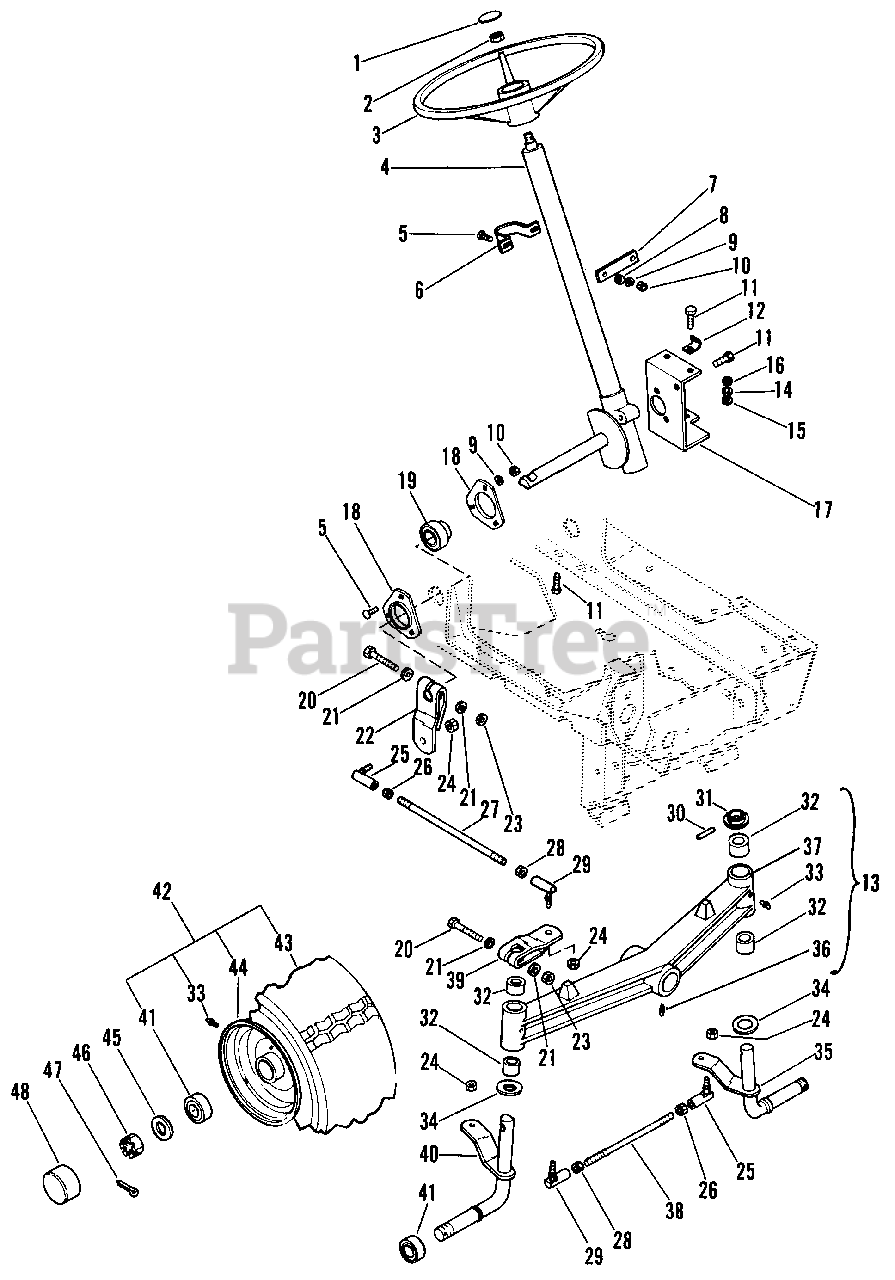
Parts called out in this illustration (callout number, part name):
1	Cap, Lens
2	Nut, Hex Jam Lock 5/8-18
3	Steering Wheel
4	Steering Gear Assembly
5	Bolt, Carriage 5/16-18 x 1.0
6	Steering Column Clamp
7	Pad
8	Washer, Flat .406 x .812 x .065
9	Washer, Lock 5/16 SP
10	Nut, Hex 5/16-18
11	Bolt, Hex 3/8-16 x 1.00
12	Clip
13	Front Axle Assembly
14	Washer, Lock 3/8 Reg.
15	Washer, Flat .438 x 1.000 x .083
16	Nut, Lock 3/8-16
17	Mounting Bracket
18	Bearing Flange
19	Bearing
20	Bolt, Hex 1/2-13 x 2.50
21	Washer, .526/.546 x .937 x .104
22	Steering Arm
23	Nut, Lock 1/2-13
24	Nut, Lock 1/2-20
25	Joint, Ball
26	Nut, Hex Jam L.H. Thd. 1/2-20
27	Drag Link
28	Nut, Hex 1/2-20
29	Ball Joint
30	Pin, Spring .250 x 1.750
31	Spindle Cap
32	Bushing, Sleeve 1 x 1-1/8 x 7/8
33	Fitting, Lube 1/4-28
34	Plastic Washer
35	L.H. Spindle
36	Fitting, Lube 90 Degree
37	Axle, Front
38	Tie Rod
39	Front Steering Arm
40	R.H. Spindle
41	Radial Bearing 1 I.D. x 2 O.D.
42	Front Tire Assembly
43	Tire, Turf Saver 8 x 6.5
44	Rim Assembly Tire Size 8 x 6.5
45	Washer, 1.000/1.031 x 1.500 x .125
46	Nut, Slotted Hex 1-14
47	Pin, Cotter .187 x 1.25
48	Front Hub Cap
